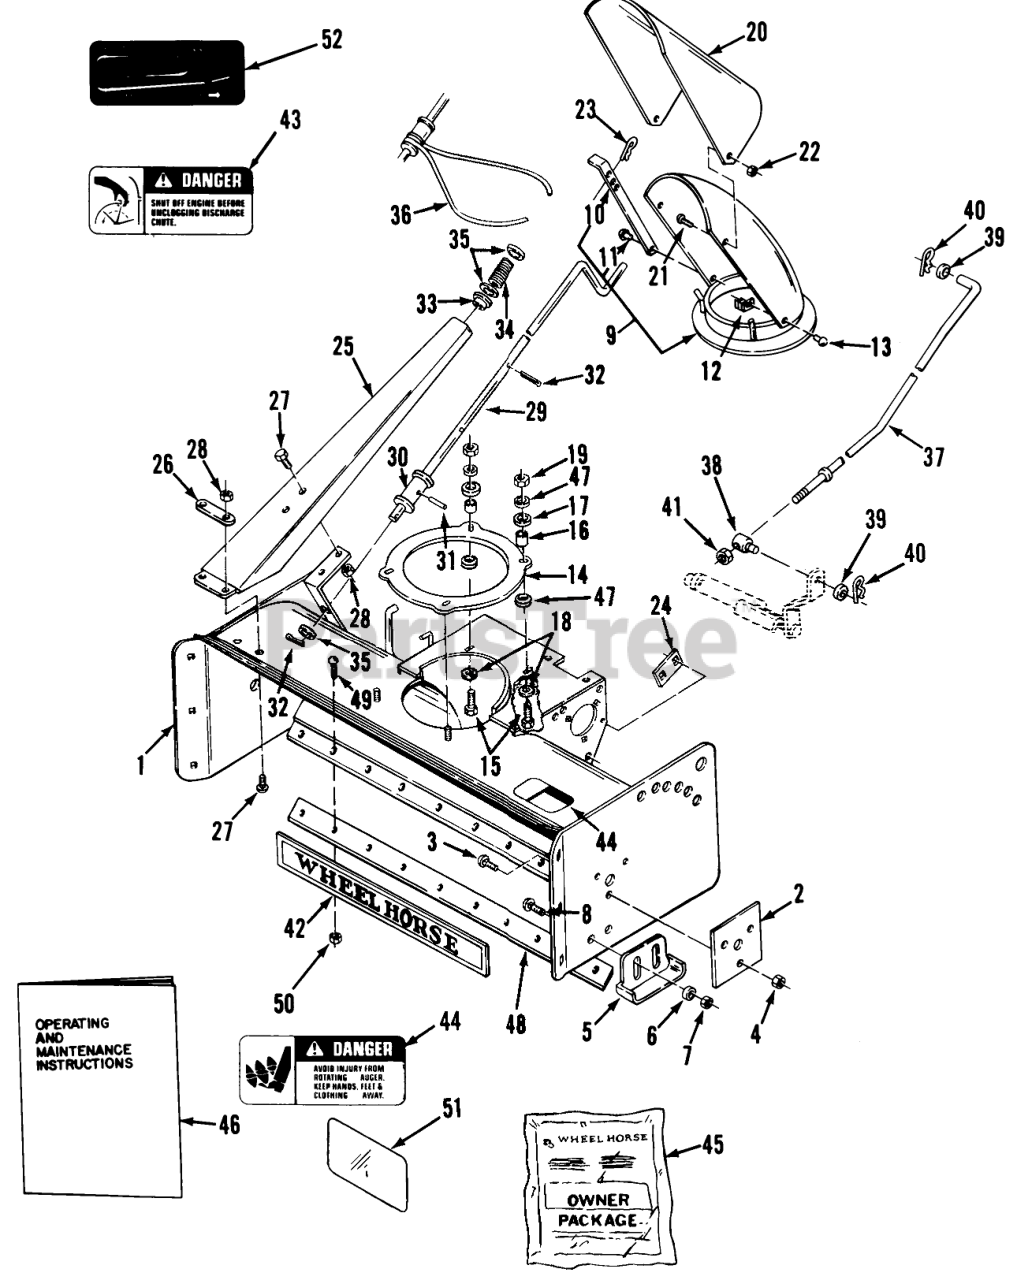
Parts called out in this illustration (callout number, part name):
1	Snow thrower Wrapper Housing
2	Plate
3	Bolt
4	Nut
5	Skid
6	Washer
7	NUT
8	Bolt
9	Shroud (includes items 10 & 11)
10	ARM R
11	RIVET
12	CLAMP
13	RIVET-4
14	COLLAR
15	Bolt
16	SPACER
17	WASHER
18	Washer
19	NUT
20	Deflector
21	MACH. SCREW
22	Nut
23	Hairpin
24	STRAP
25	Crank Support
26	Bar-Reinforcing
27	Bolt
28	NUT
29	CRANK R
30	ASSY TUBE CRANK R
31	ROLL PIN 1/4 X 1-1/4
32	Pop Rivet
33	NYLINER BUSHING
34	SPRING-COMPRESSION
35	Washer
36	CABLE
37	ROD-LIFT B
38	TRUNION
39	Washer
40	Hairpin Cotter
41	Nut
42	DECAL WHEEL HORSE
43	DECAL DANGER
44	DECAL DANGER
45	Loose Parts Package
46	Owner-s Manual
47	WASHER
48	Reversible Scraper
49	Bolt-Carriage
50	Nut
51	DECAL-OVERLAY
